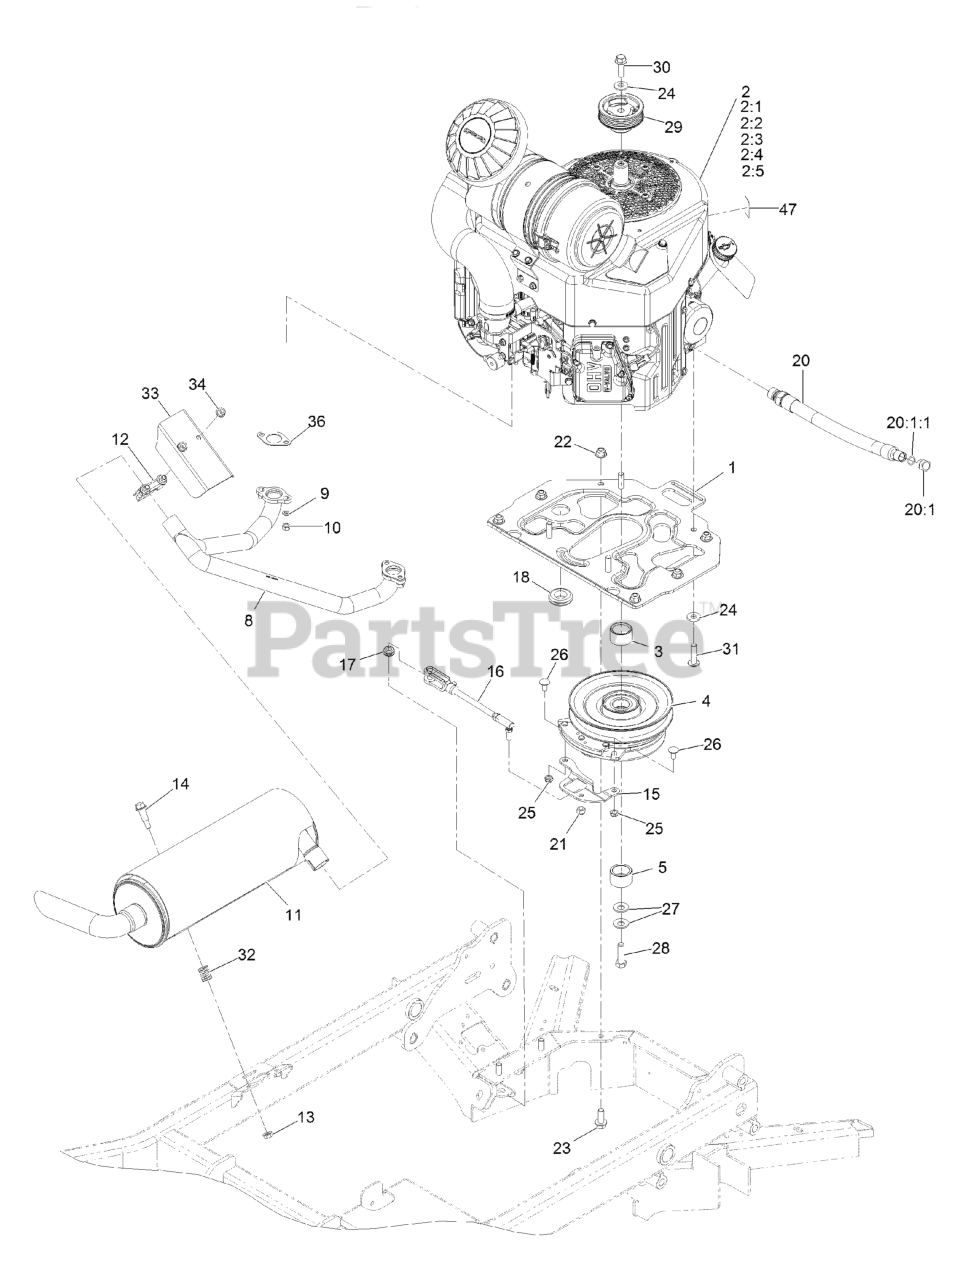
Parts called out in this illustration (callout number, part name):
1	PLATE, ENGINE
2:1	Kawasaki 49065-7007 Engine Oil Filter
2:2	Kawasaki 49019-0027 Fuel Filter
2:4	Kawasaki 11013-7045 Pre-Filter
2:5	Kawasaki 11013-7044 Air Filter
3	SPACER, CLUTCH
5	SPACER, CLUTCH
8	HEADER, KAWASWAKI
9	WASHER-LOCK
12	CLAMP-MUFFLER
14	Bolt-Shoulder
15	STRAP, CLUTCH
16	ASM, CLUTCH ANCHOR
17	GROMMET
18	GROMMET
20	ENGINE OIL DRAIN HOSE ASM
20:1	PLUG-HH
20:1:1	O-RING
21	NUT-LOCK
22	NUT-HF, NI
23	SCREW-HHF 3/8-16 X 1
24	WASHER-BELLEVILLE
25	NUT-LOCK, NI
26	SCREW-CARR
27	WASHER-SPRING
28	SCREW-HH 7/16-20 X 1 1/2 W/LOCTITE
29	PULLEY, CRANK
30	Screw-HH, Patch
31	SCREW-BHTF
32	SPRING, COMPRESSION
33	SHIELD, HEAT
36	GASKET-EXHAUST
47	DECAL-10W-50 OIL
